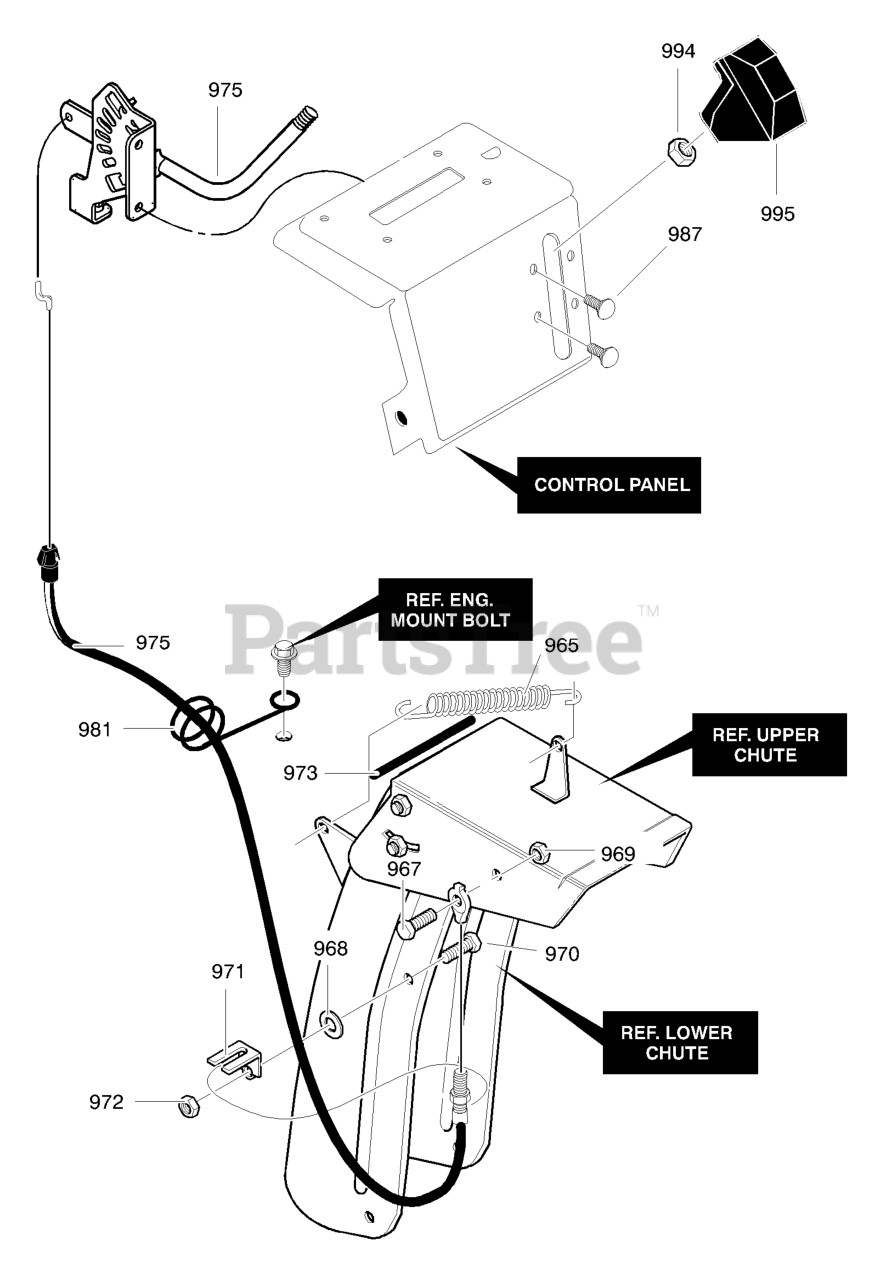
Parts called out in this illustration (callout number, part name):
965	TENSION SPRING
967	BOLT, SHOULDER
968	FLATWASHER
970	SCREW, 5/16-18 x 0.75
971	BRACKET, CABLE CHUTE
972	NUT, 5/16-18
973	TRIM STRIP, BLACK
975	CABLE, CHUTE DEFLECTOR
981	WIRE FORM, REMOTE CHUTE CABLE
987	SCREW, 1/4-20 x 0.38
994	NUT, 3/8-16
995	GRIP, LEVER
